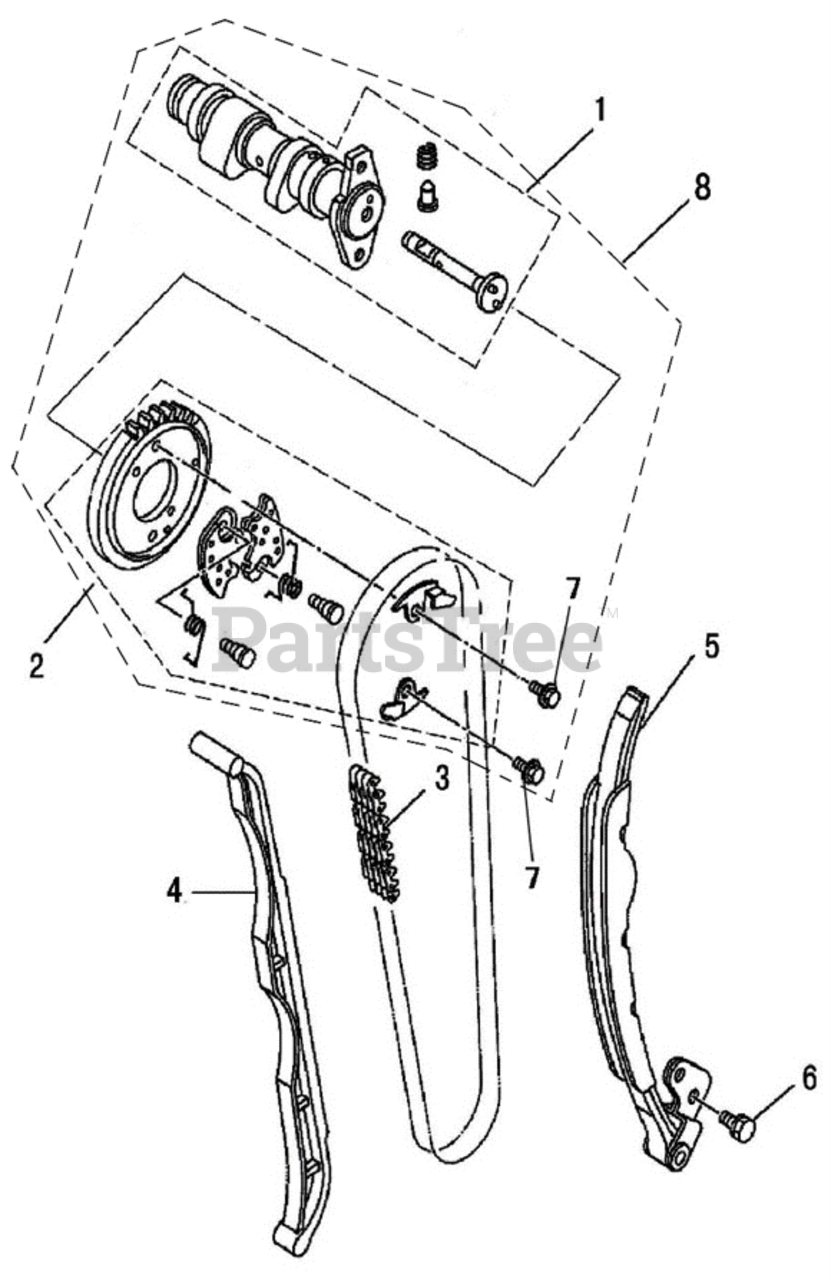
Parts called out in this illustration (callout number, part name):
1	Camshaft assy
2	Timing Driven Sprocket assy
3	Timing Chain M7-6.35-130
4	Guide Plate
5	Tensioner Plate
6	Hexagon head bolt and plain washer assemblies M6X16
7	Hexagon flange bolts M7X11
8	Camshaft Assembly
